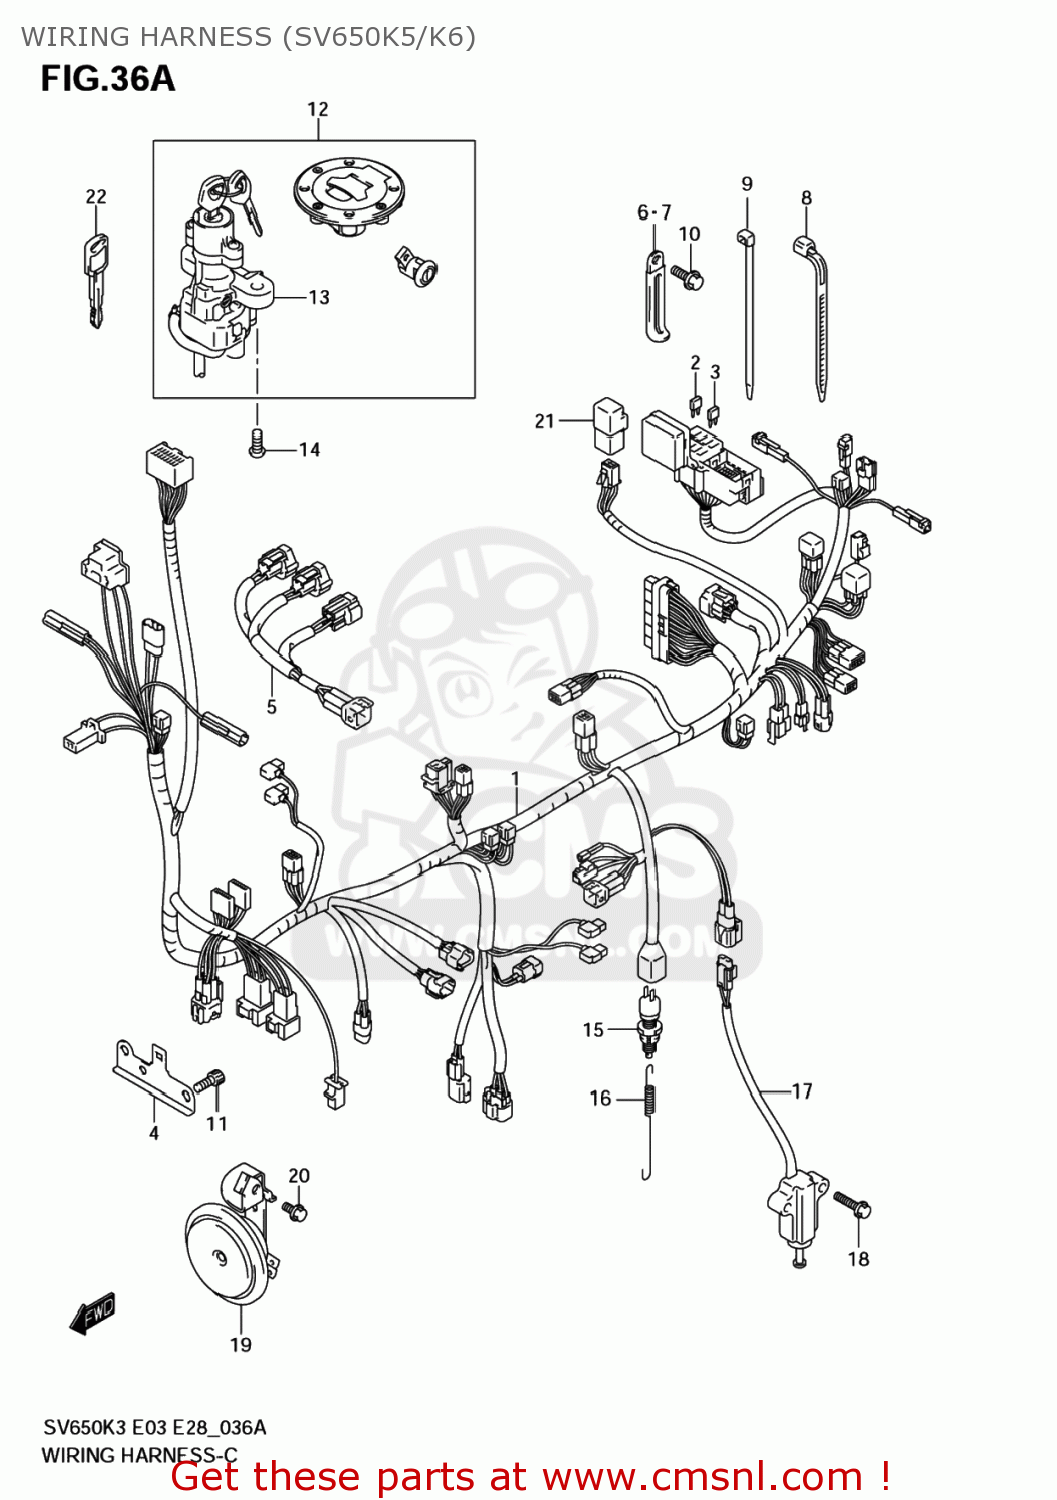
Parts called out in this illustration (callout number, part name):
1	HARNESS, WIRING
2	FUSE(10A)
3	FUSE(15A)
4	HOLDER,COUPLER
5	WIRE,INJECTOR LEAD
6	CLAMP(L:45)
7	CLAMP(L:80)
8	CLAMP(L:95)
9	CLAMP(L:145)
10	BOLT
11	BOLT,VAC.PIPE
12	LOCK SET
13	LOCK ASSY,STEE
14	BOLT(8X20)
15	SWITCH ASSY,STOP LAMP
16	SPRING
17	SWITCH ASSY,SIDE STAND
18	BOLT
19	HORN ASSY
20	BOLT
21	RELAY ASSY
22	KEY,BLANK
